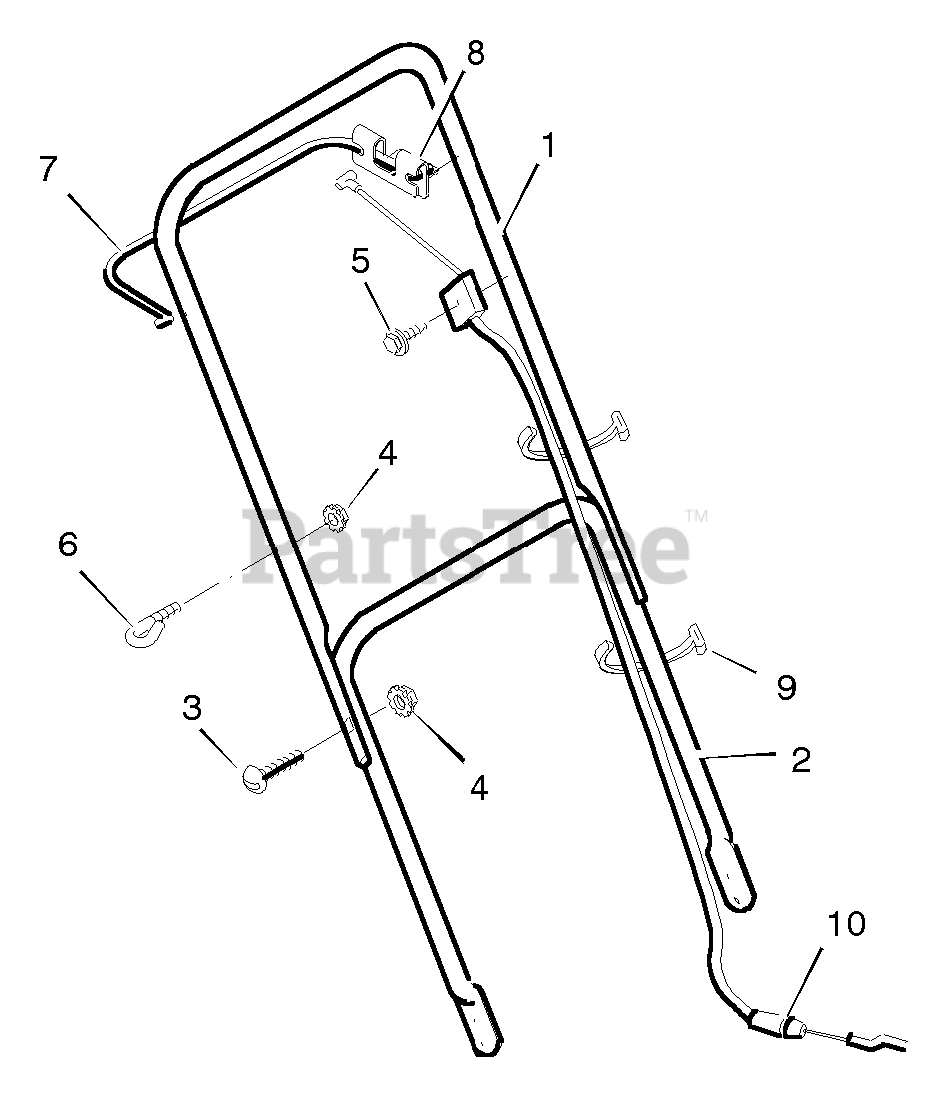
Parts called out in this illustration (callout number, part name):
1	Handle, Upper - Straight (Gray)
2	Handle, Lower (Gray)
4	Locknut
6	GUIDE, ROPE
7	Engine Stop Lever - Straight
8	Bracket, Stop Lever
9	Fastener, Cable
10	Engine Stop Cable
